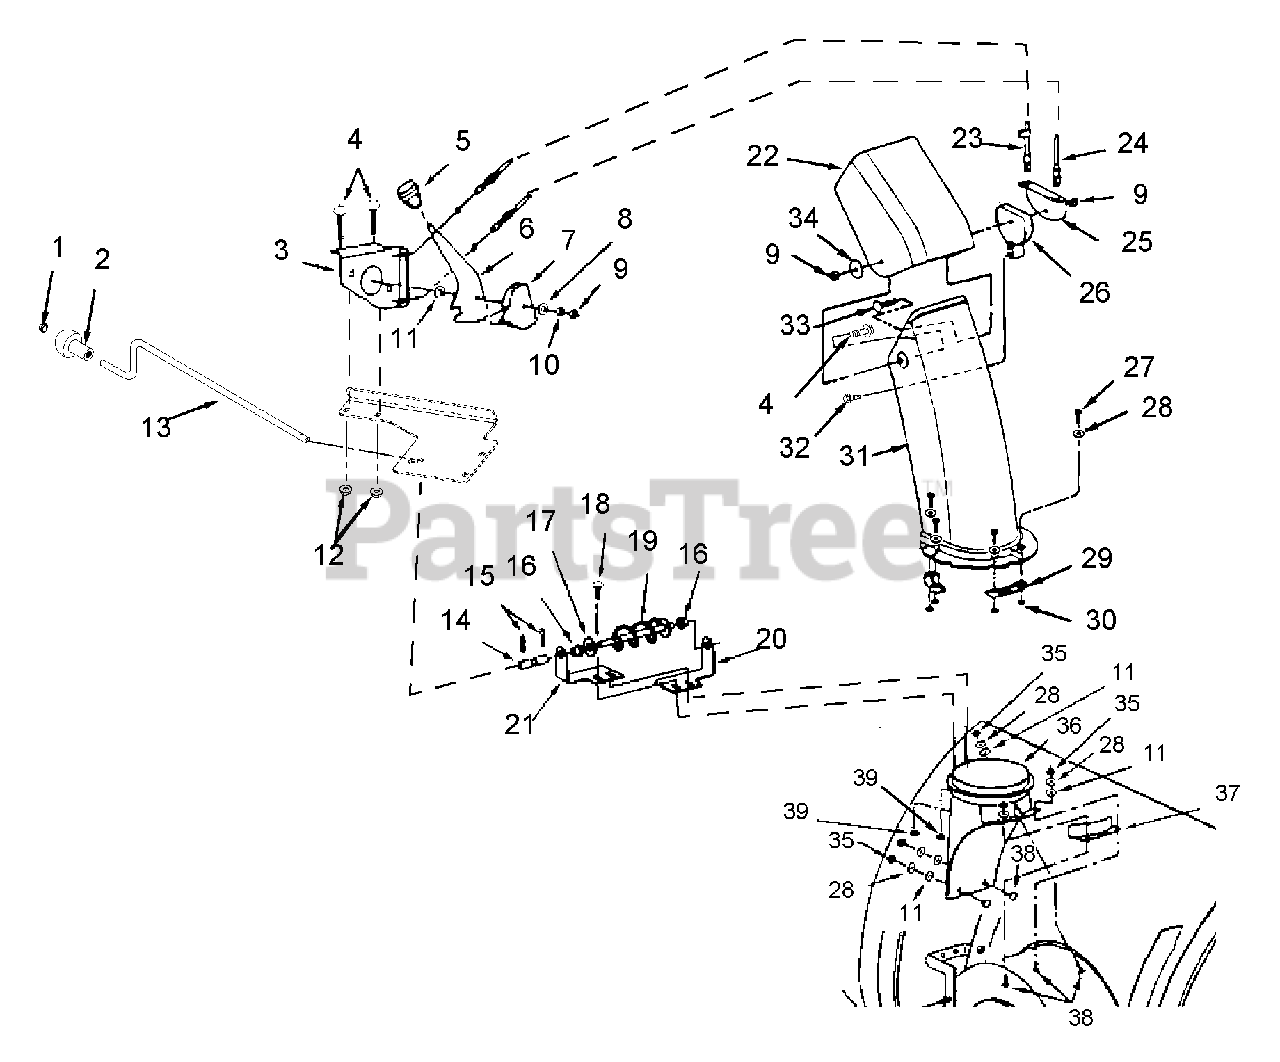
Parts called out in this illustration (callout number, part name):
1	Cap, .38 Rod
2	Knob
3	Assembly, Chute Tilt Bracket
4	Bolt-Round Head Square Neck .31-18 x .75 Grade 5
6	Handle, Chute Tilt
7	Guide, Cable
8	Washer, 5/16
9	Nut, Hex Lock 5-16-18
10	Washer-Locking .31 x .078 Regular
11	Washer-Flat-Nylon .375 x .75 x .060
12	Nut-Locking-Top-Flange .31-18
13	Crank, Chute
14	U-Joint
15	Roll Pin, 1/8 x 5/8
16	Plastic Bushing, 3/8
17	Flat Washer, 3/8
18	Carriage Bolt, 5/16-18 x 1
19	Chute Crank Assembly
20	Chute Crank Bracket, Front
21	Chute Crank Bracket, Rear
22	Chute, Upper
23	Cable, Chute Control with Clip
24	Cable, Chute Control
25	Bracket, Cable
26	Guide, Cable
27	Hex Bolt, 1/4-20 x 1
28	Washer, 1/4
29	Chute Keeper
30	Hex Lock Nut, 1/4
31	Chute, Lower
32	Screw-Machine .25-20 x .75 Hex Washer Head
33	Carriage Bolt, 5/16-18 x 1-1/2
34	Washer, 5/16
35	Hex Lock Nut 1/4-20
36	Chute Adapter
37	Chute Reinforcement
38	Carriage Bolt, 1/4-20 x 3/4
39	Nut-Locking-Top-Flange .31-18
